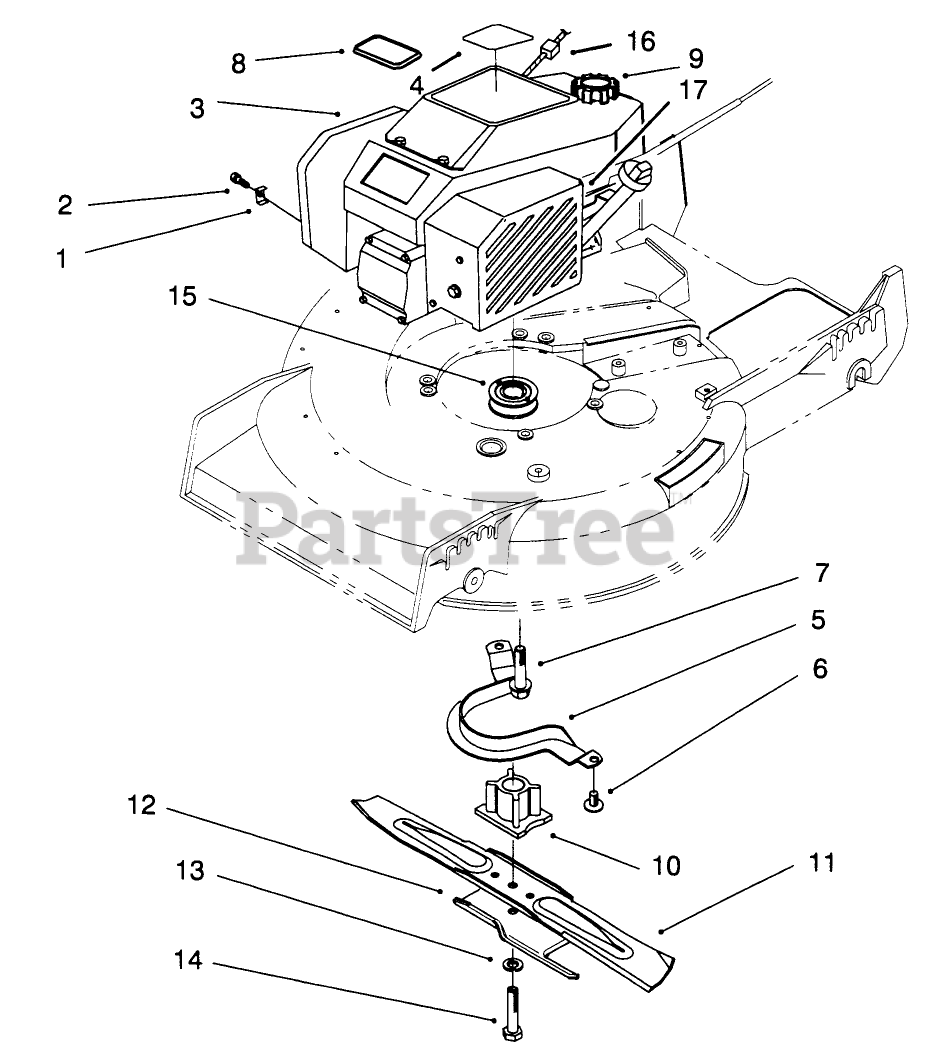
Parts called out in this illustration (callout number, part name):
1	CLAMP-CASING
2	CLAMP SCREW F/W ENGINE
6	SCREW-HWHTF
7	SCREW-HWH
10	BLADE RETAINER
13	WASHER-LOCK
14	SCREW-BLADE
15	PULLEY-DRIVE, ZONE START
16	STOP-ROPE
17	COVER - BRAKE F/W
